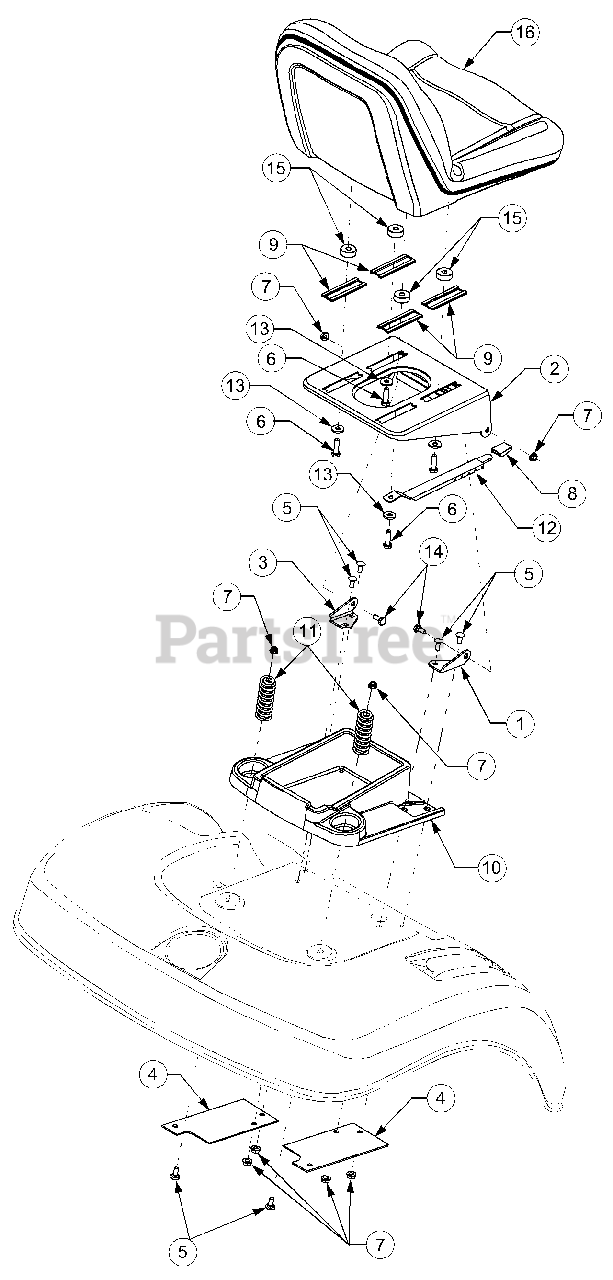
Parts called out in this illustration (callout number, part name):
6	Screw, Hx Cap Lock, 3/8-16 x 1.5 GR5
7	Nut, Hex Flange Lock, 5/16-18
8	Knob, Seat Adjuster
9	Slide, Seat
10	Tray, Tool
11	Spring, Comp, 1.9 OD x 2.4
12	Index Spring, Seat Adjuster
13	Washer, Flat, .406 x 1.0 x .105
14	Bolt, Shoulder
15	Spacer, Seat Slide Shoulder
16	Seat, High Back
